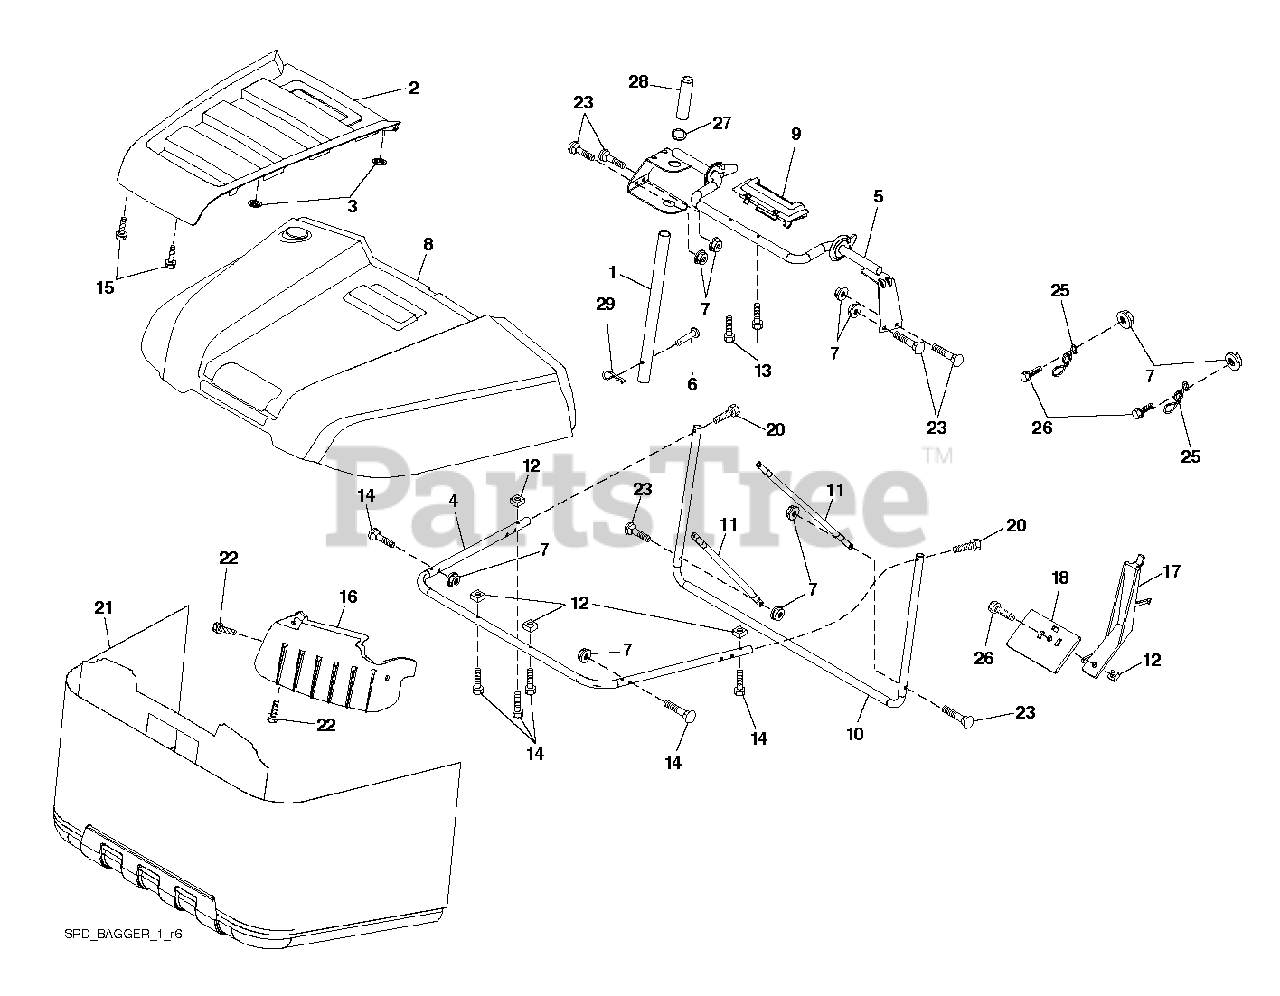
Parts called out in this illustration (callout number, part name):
1	TUBE.HANDLE.BAGGER.CRD/SRD.BLA
2	APPLIQUE.TOP.BAG.SRD.ORANGE
3	NUT.PUSH.156
4	SUBASM.TOP.TUBE.TEX.CRD
5	FRAME.ASM.TOP.BAGGER.SRD
6	RIVET,DRILLED
7	NUT T
8	BAGGER.TOP.SRD.APPLIQUE
9	INSERT.HANDLE.BAGGER.(2 2)
10	FRAME.FRONT.SRD.BAGGER
11	TUBING.BRACE.BAGGER.SRD.BLACK
12	NUT.SQUARE.1/4
13	SCREW.1/4X1.150.HXWSH
14	BOLT.SHOULDER.HX.WSH.1/4X1.150
15	SCREW,#8.FLAT.HEAD.DRILL.TIP
16	DEFLECTOR.BAGGER.SRD
17	LEVER.BAGGER.FULL.SRD.BLACK
18	PADDLE.BAGGER.FULL.SRD.BLACK
20	SCREW.HEXCAP.1/4-20X1.375(2 2)
21	BAG.ASM.BAGGER.SRD.HUSQVA.GREY
22	SCREW.HI-LO.CONSOLE
25	SPRING.LATCH.BAGGER.SRD
26	SCREW HEX CRT
27	RB GROMMET.RUBBER.SRD
28	GRIP.HANDLE.BLACK
29	PIN.COTTER.5/16.BOW TI
